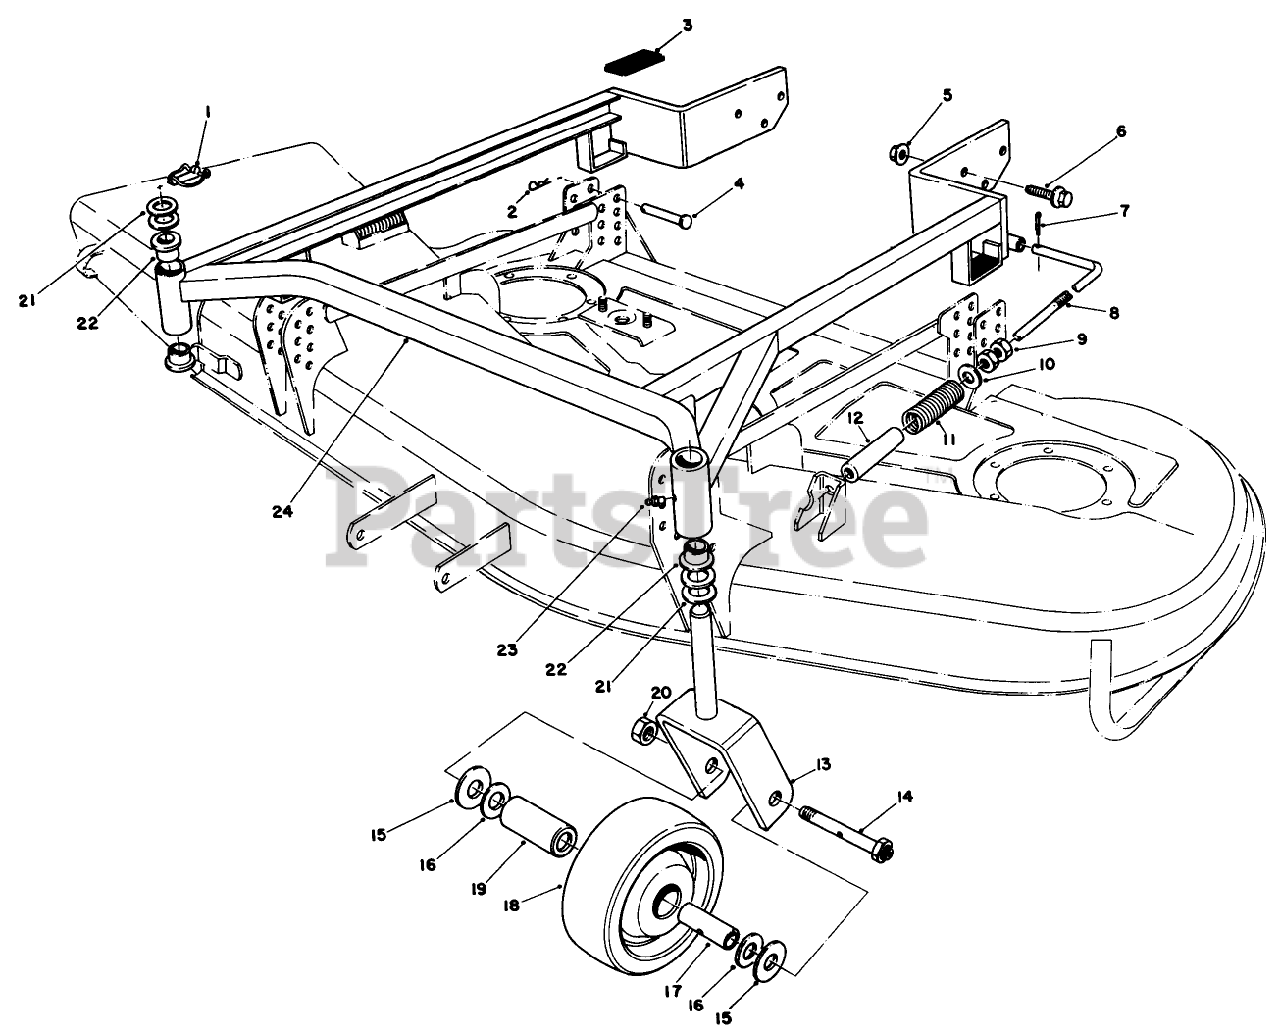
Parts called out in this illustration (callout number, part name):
1	PIN-LYNCH
2	PIN-HAIR
4	PIN-CLEVIS
5	NUT-LOCK, FLANGE
6	SCREW-HHF
7	PIN-COTTER
9	NUT-JAM
10	WASHER
11	SPRING-COMPRESSION
15	THRUST WASHER
16	BEARING RETAINER
19	ROLLER BEARING
20	NUT-HEX
21	WASHER-THRUST
23	FITTING-GREASE
